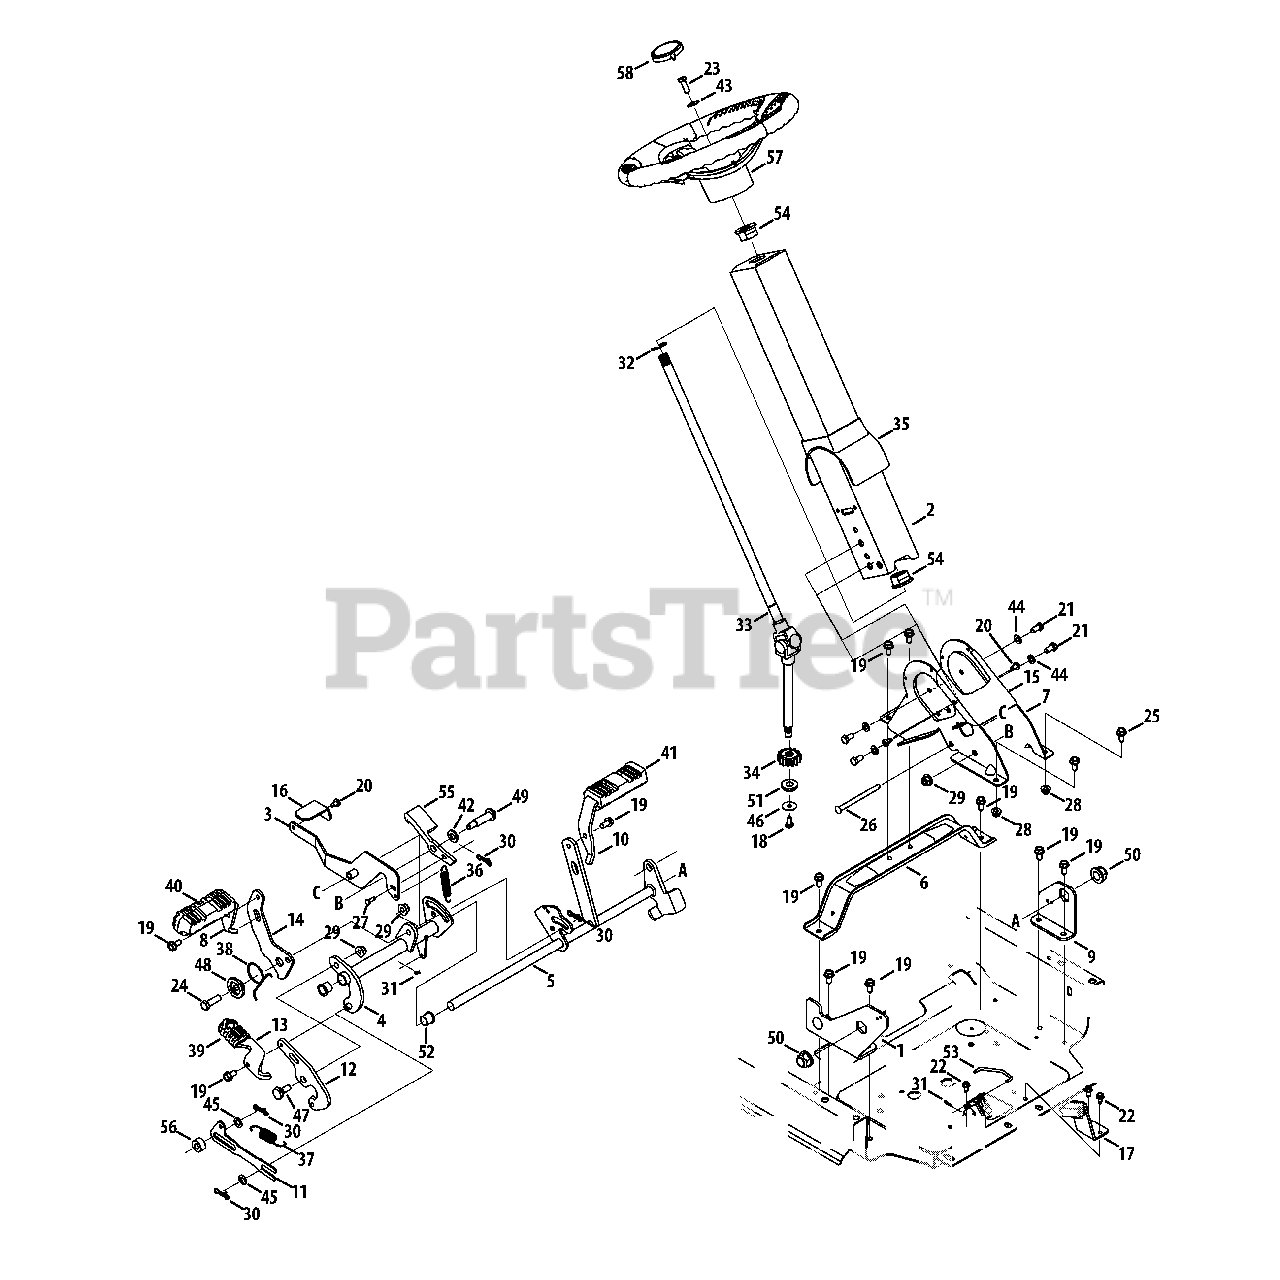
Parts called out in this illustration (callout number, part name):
1	Support Bracket Assembly, RH
2	Steering Column Assembly
3	Brake Pedal Assembly
4	Drive Pedal Assembly
5	Brake Pedal Assembly
6	Steering Support Bracket
7	Lower Steering Wheel Column
8	Drive Pedal
9	Support Bracket, LH
10	Brake Pedal
11	Return to Neutral Link
12	Reverse Pedal Bracket
13	Reverse Pedal
14	Forward pedal Bracket
15	Lower Column Cover
16	Tilt Steering Pedal
17	Brake Switch Mounting Bracket
18	Hex Head Screw, 1/4-20 x .625
19	Hex Washer Screw, 5/16-18 x .750
20	Screw, 1/4-20 x .5
21	Hex Screw, 5/16-18 x .625
22	Hex Washer Screw, 1/4-20 x .500
23	Hex Screw, 5/16-24 x.875
24	Hex Screw, 3/8-16 x 1.25
25	Hex Screw, 5/16-18 x .75
26	Clevis Pin, 5/16 x 4.135
27	Clevis Pin, .224 Dia. x .625
28	Flange Lock Nut, 5/16-18
29	Flange Lock Nut, 3/8-16
30	Bow-Tie Cotter Pin, 72
31	Cotter Pin, .047 Dia. x .59
32	E-Ring, .750
33	Steering Shaft
34	14-Tooth Spur Gear
35	Column Cover
36	Extension Spring, .500 x 2.733 LG
37	Extension Spring, .70 OD x 3.035 LG
38	Torsion Spring, 1.00 ID x .22
39	Reverse Pedal Pad
40	Forward Pedal Pad
41	Brake Pedal Pad
42	Flat Washer, .535 x .930 x .090
43	Bell Washer, .340 x .872 x .060
44	Flat Washer, .330 x .630 x .064
45	Thrust Washer, .375 x .700 x .030
46	Flat Washer, .265 x 1.00 x .030
47	Shoulder Bolt, 3/8-16 x .500 x .270
48	Shoulder Spacer, 1.50 x .38 x .38
49	Shoulder Screw, 3/8-16 x .496 x 1.445
50	Hex Flange Bearing
51	Hex Flange Bearing, 7/16
52	Flange Bearing, .63 ID x .695 OD x .06
53	Throttle Sensor Actuator Rod
54	Flange Bearing, .63 ID x 1.50
55	Cruise Latch
56	Spacer, .385 ID x .875 OD x .458
57	Steering Wheel Assembly
58	Steering Wheel Cover
